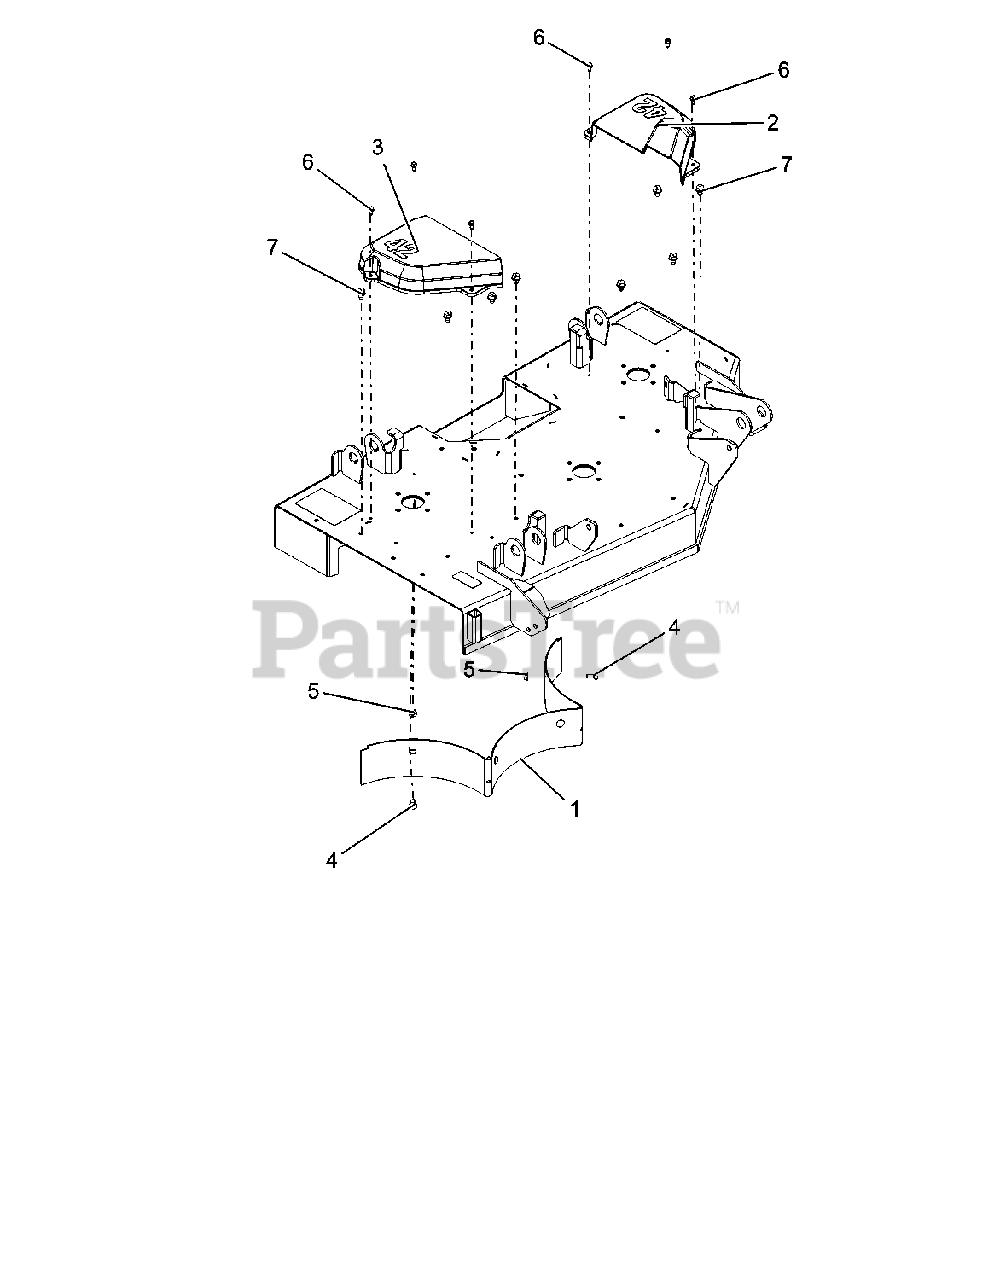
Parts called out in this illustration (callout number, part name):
1	BAFFLE, REAR 42"-RED
2	COVER, BELT 42" LEFT
3	COVER, BELT 42" RIGHT
4	BLT-RDHDSQNK .31-18X.75 G5 YWZC
5	NUT, LK-TOP-FLG .312-18 YWZC
6	SCR-TAP .25-20X.50 HWH TR YWZ
7	SCR-TAP .38-16X.50 HWH TR YWZ
